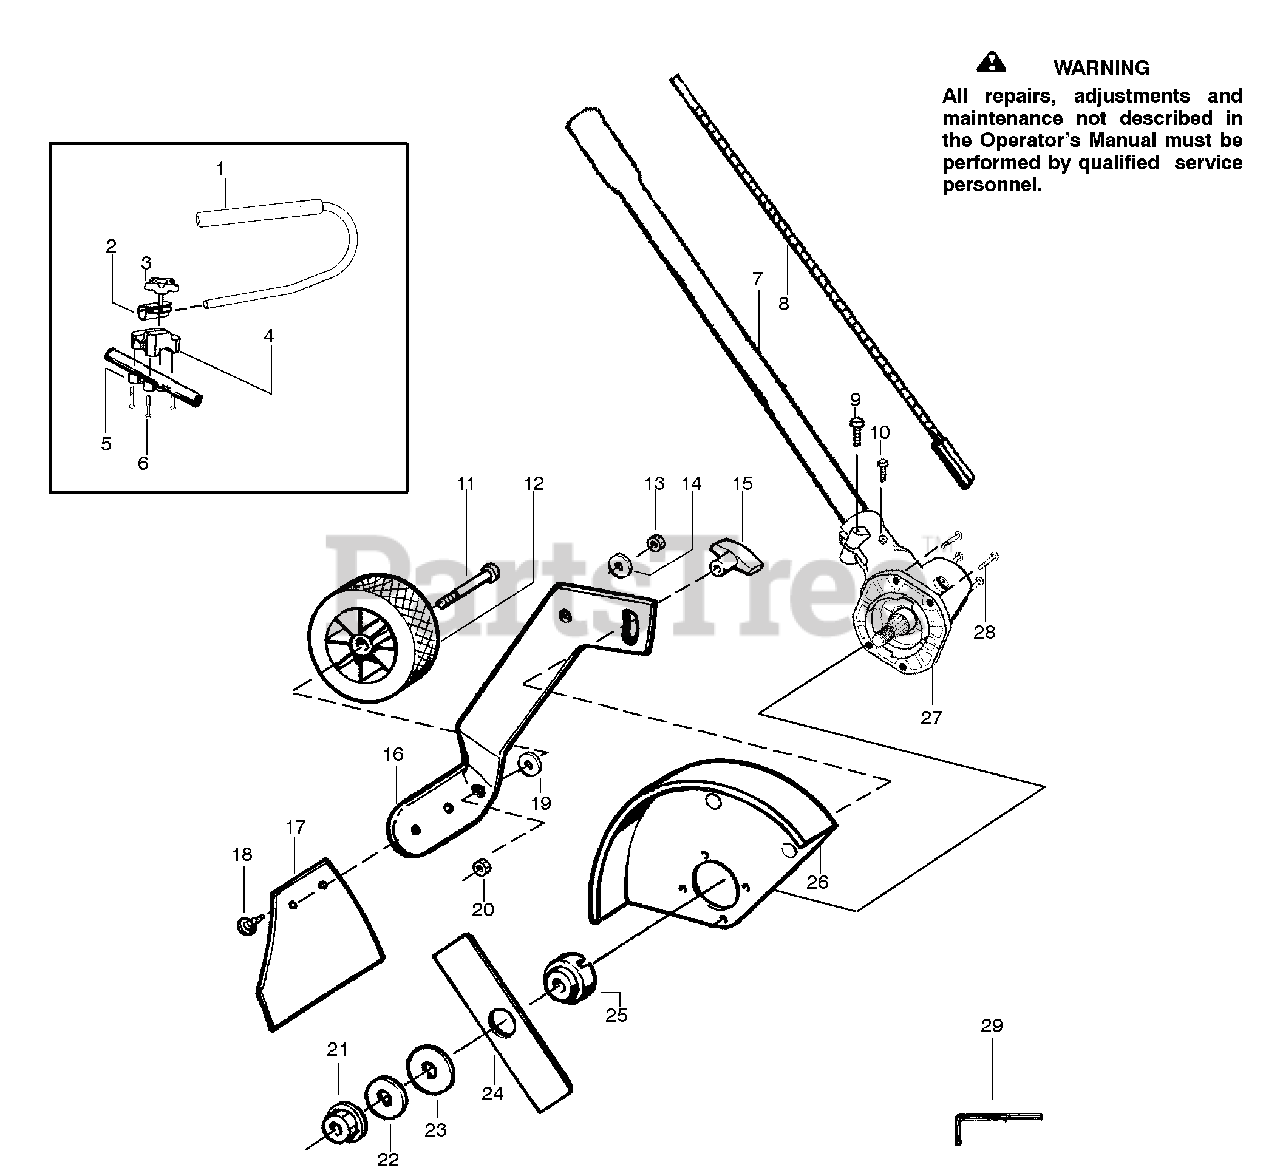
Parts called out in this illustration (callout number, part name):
1	Kit - Handlebar
2	Clamp - Handlebar
3	Knob
4	Base - Clamp
5	Kit - Clamp - Tube
7	Assy. - Driveshaft
8	Flexshaft - Split boom
10	Screw - Alignment
11	Bolt - Shoulder Axle
12	Wheel - 4"
16	Bracket - Adj. Wheel
17	Kit - Mud Flap
18	Fastener - Mud Flap
21	Nut - Flange
22	Washer - Belleville
23	Washer - Flat
26	Kit - Edger Guard
27	Kit - Gearbox
29	Wrench - Hex
